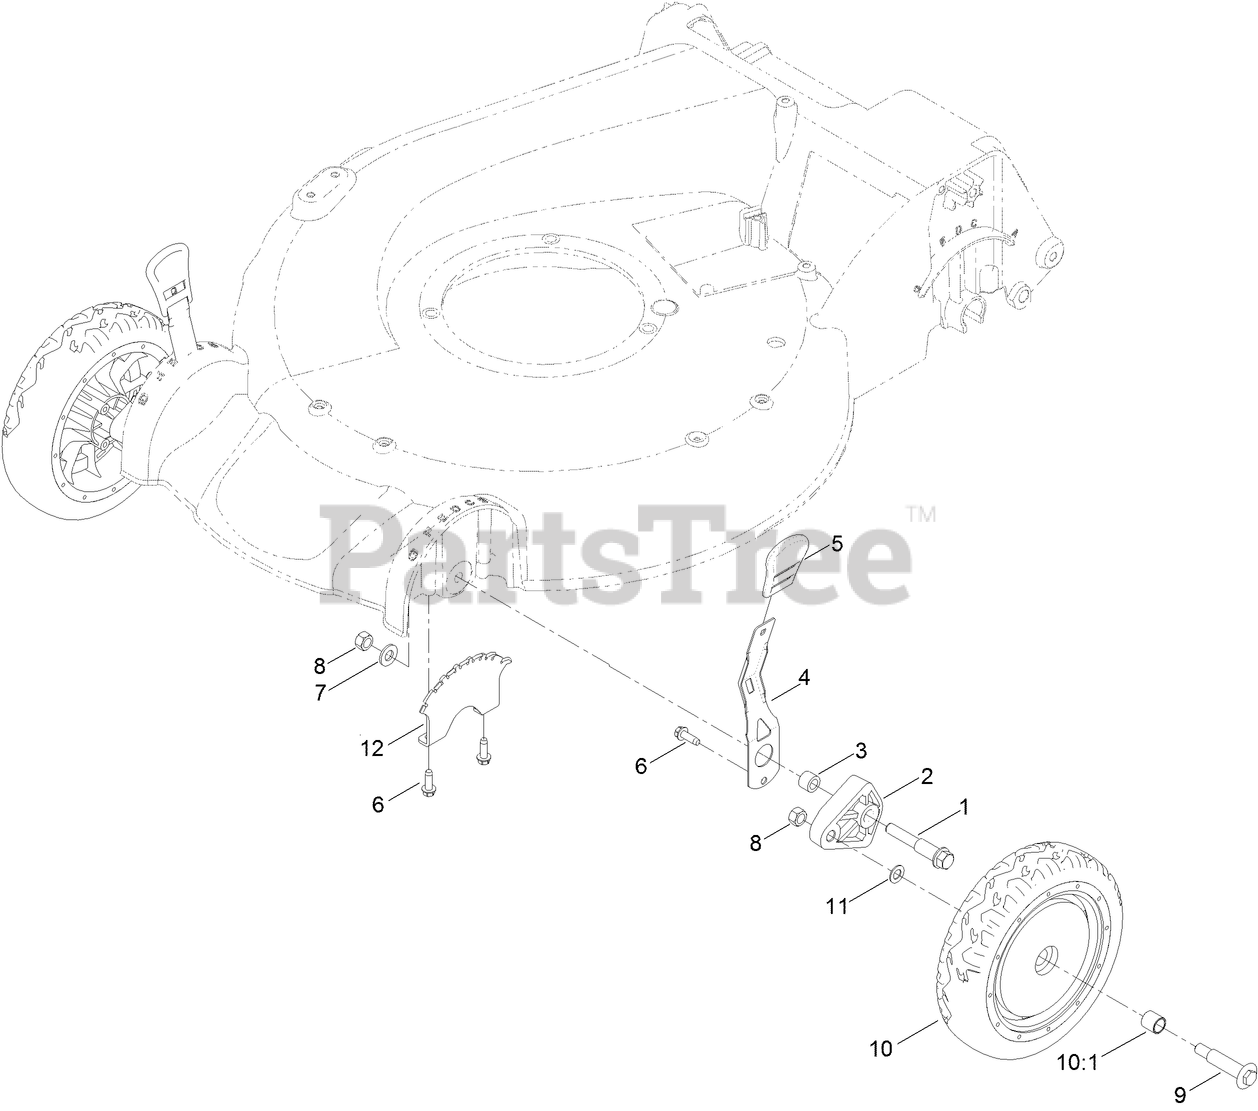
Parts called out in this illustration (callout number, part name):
1	SCREW-SHOULDER
2	ARM-PIVOT
3	SPACER-WHEEL
4	ARM-SPRING
5	KNOB-HOC
6	SCREW-HWHTF
7	WASHER-FLAT
8	NUT-HEX
9	BOLT-SHOULDER
10	8 INCH WHEEL ASM
10:1	BUSHING
11	WASHER
12	PLATE-HOC
